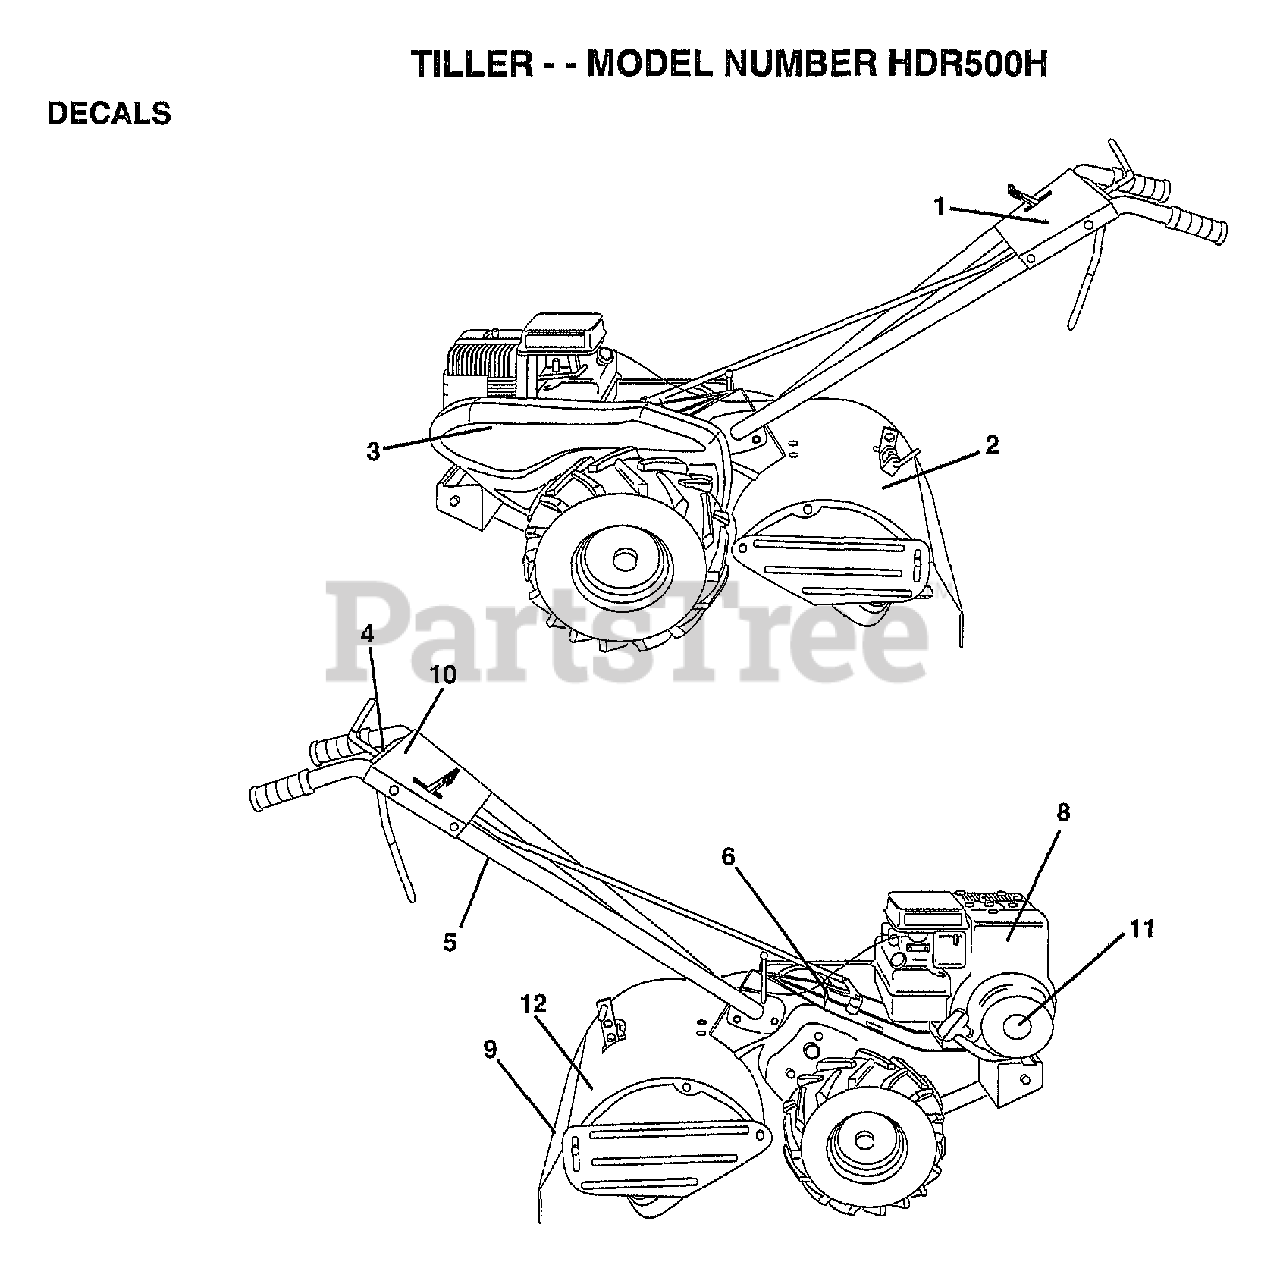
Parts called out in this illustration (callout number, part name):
1	"DECAL PANEL,CTRL"
2	"DECAL SHIELD,TINE"
3	DECAL.LOGO
4	DECAL.CONTROL
5	DECAL.HAND.PLACE
6	DECAL CRT
9	DECAL.WARN.ROT.TI
10	DECAL REVERSE
12	DECAL.TINE.SHIELD
